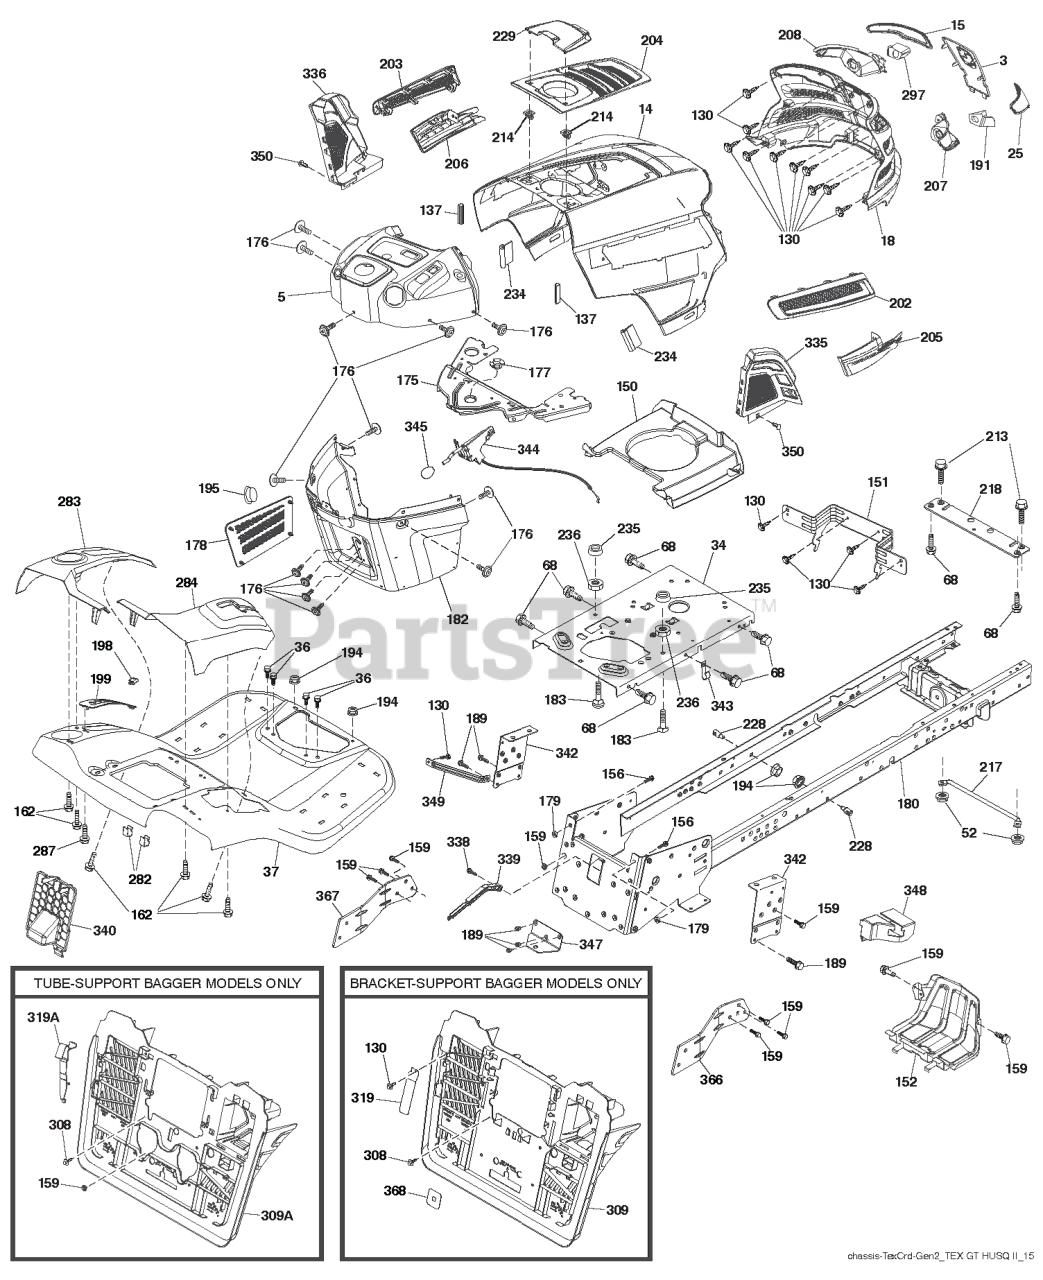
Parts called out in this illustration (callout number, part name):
3	APPLIQUE.SUBASM.GT.HUSQ.II
5	DASH.HUSQ2.SM.E.NC.HR.CHG.498
14	HOOD.ASM.HUSQVARNA.GT.TEX.ORAN
15	LENS.HEADLIGHT.LH.GTII.2011
18	GRILLE.SUBSTRATE.2011.
25	LENS.HEADLIGHT.RH.GTII.2011
34	PLATE.ENGINE.WELDED.CHASSIS
36	SCREW 5/16"
37	FENDER.TEX.SRD.CRD.BASE
52	LOCKNUT
68	Screw 5/16-18 x 1/2 Hex, Self Tapping 5/16-18 x 1/2
130	SCREW.#10 X 0.750.BOS
137	BUMPER DASH
150	AIR.DUCT.GTV.BLACK
151	BRACKET.PIVOT.HOOD.GT.HUSQ.II
152	SHIELD.BROWNING.PNT.GT.V2
156	BOLT
159	SCREW, 3/8-16X3/4
162	SCREW.HI-LO.CONSOLE
175	PLATE.CROSSMEMBER.HUSQ
176	SCREW.#10-24X5/8.RN.QU
177	BUSHING, STEERING
178	CARGO.ASM.NET.TXGT.W/C
179	NUT
180	WELDMENT.CHASSIS.TEX.CRD.GEN.2
182	DASH DASH LOWER
183	BOLT.5/16-18X1-1/4 FULL THD
189	SCREW
191	INSERT.REFLECTIVE.RH.HUSQ.GTII
194	NUT LOCK HEX FLANGE 5/16-18
195	PLUG.HOLE.DASH.LOWER.12V.BLK
198	INDICATOR.DECK.LIFT.RED
199	PLATE DECK LIFT
202	VENT.SIDE.RH.GT.HUSQ.II.
203	VENT.SIDE.LH.GT.HUSQ.II.498
204	VENT.TOP.EXTERNAL.FILL.GT2.GRE
205	SIDE.TRIM.RH.GT.HUSQ.II
206	SIDE.TRIM.LH.GT.HUSQ.II.GRAY
207	BEZEL LIGHT.RH.GT.II.MYLAR
208	BEZEL LIGHT.LH.GT.II.MYLAR
213	BOLT
214	CLIP.RETAINER.TINNER.
217	ROD.PIVOT.HOOD
218	X-PIECE.HOOD.STOP.NON/
228	STUD.FASTNER.W/ANTI-ROTATE
229	LID.EXT.FILL.GT.HUSQ2.BLACK
234	BUMPER.HOOD.TEX.HUSQVARNA
235	SPACER FENDER
236	NUT.CENTERLOCK.5/16-
282	CLIP.RETAINER.CONSOLE.LT.HUSQ
283	CONSOLE.DECKLIFT.CRDII.498
287	SCREW 1/4X20
297	INSERT.REFLECTIVE.LH.HUSQ.GTII
308	BOLT.5/16-18UNCX3/4 W/SEMS.BLK
309	BACKPLATE.SUBASM.SERV.TEX.CRD.
319	LEVER.BAGGER.TEX.CRD.GEN.BLACK
335	COVER.LOWER.DASH.RH.BLACK
336	COVER-LH.LOWER.DASH.GT2.BLACK
338	BOLT BOLT SHOULDER
339	LEVER LEVER BAGGER
340	BATTERY.DOOR.TEX.CRD.GEN.2,1
342	SUPPORT SUPPORT FENDER
343	CLIP CLIP
344	CONTROL.EZ.MULCH.TEX/CRD
345	RP KNOB.OVAL.TAPERED.3/8-16BLK
347	HITCH TOW
349	BRACKET.SUPPORT.LRVB/CRD
350	CLIP.X-MAS.TREE
366	BRACKET.RH.FRONT.BAGGER.BLACK
367	BRACKET.LH.FRONT.BAGGER.BLACK
368	FULL.LEVER.BAGGER.TEX.CRD
